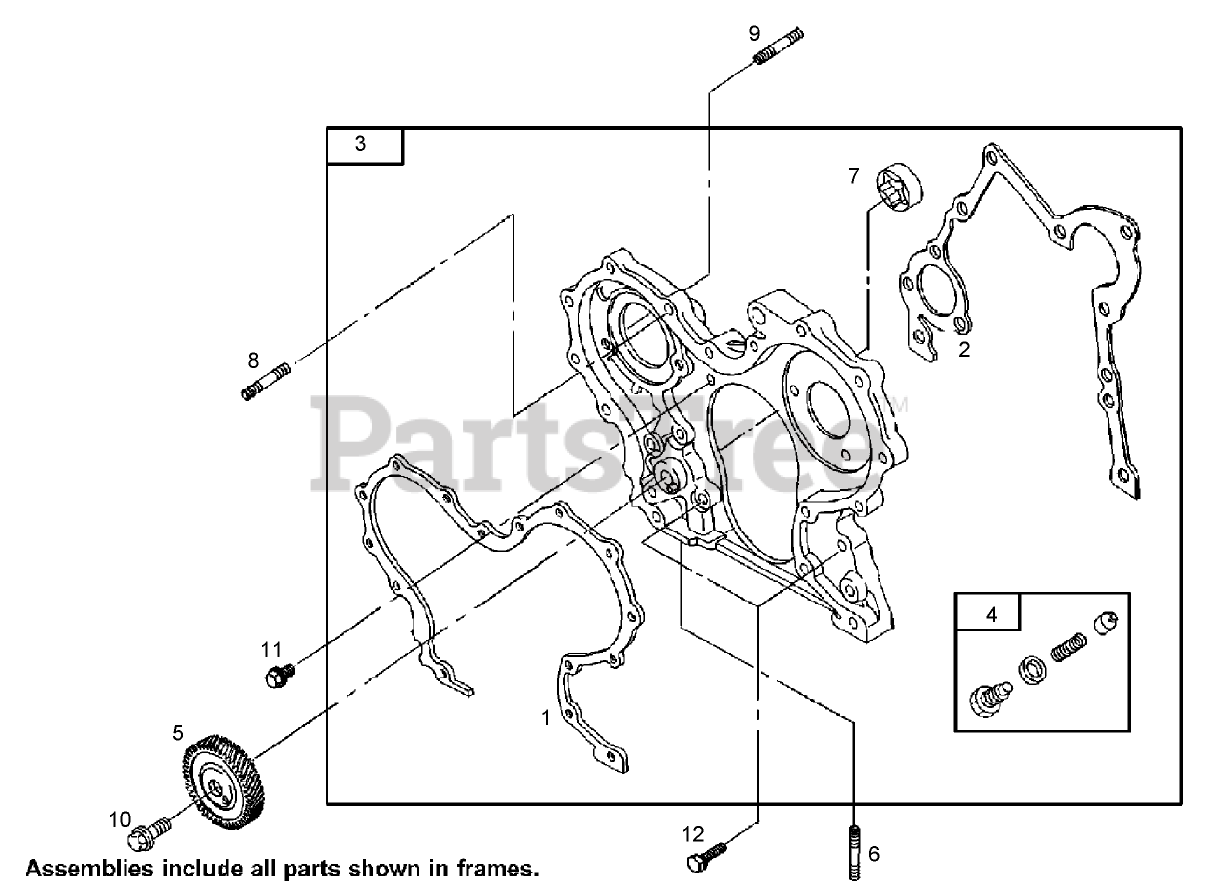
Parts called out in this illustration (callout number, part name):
1	GASKET-COVER, GEAR
2	GASKET-COVER, GEAR
3	HOUSING-GEAR
4	VALVE-RELIEF, OIL
5	GEAR-DRIVE
6	STUD-METRIC
7	Gerotor
8	STUD-METRIC
9	STUD-METRIC
10	SCREW-HEX
11	SCREW-HEX
12	SCREW-HEX
